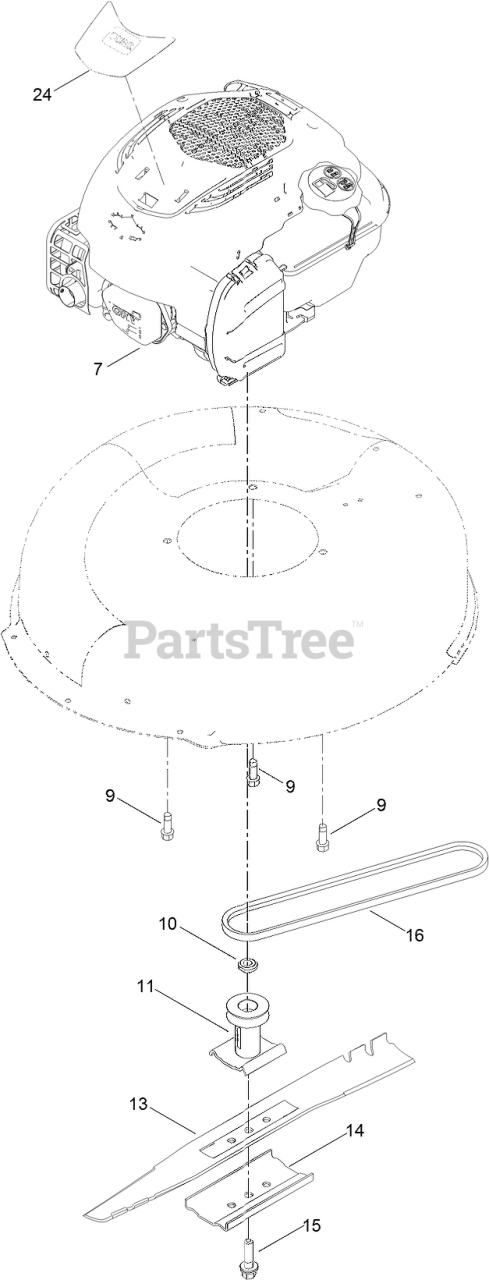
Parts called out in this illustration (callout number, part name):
9	SCREW-TAPTITE
10	SPACER-DRIVER
11	DRIVER-BLADE
13	BLADE-21IN
14	SUPPORT-BLADE
15	BOLT-BLADE
16	V-BELT
24	DECAL-SHROUD
